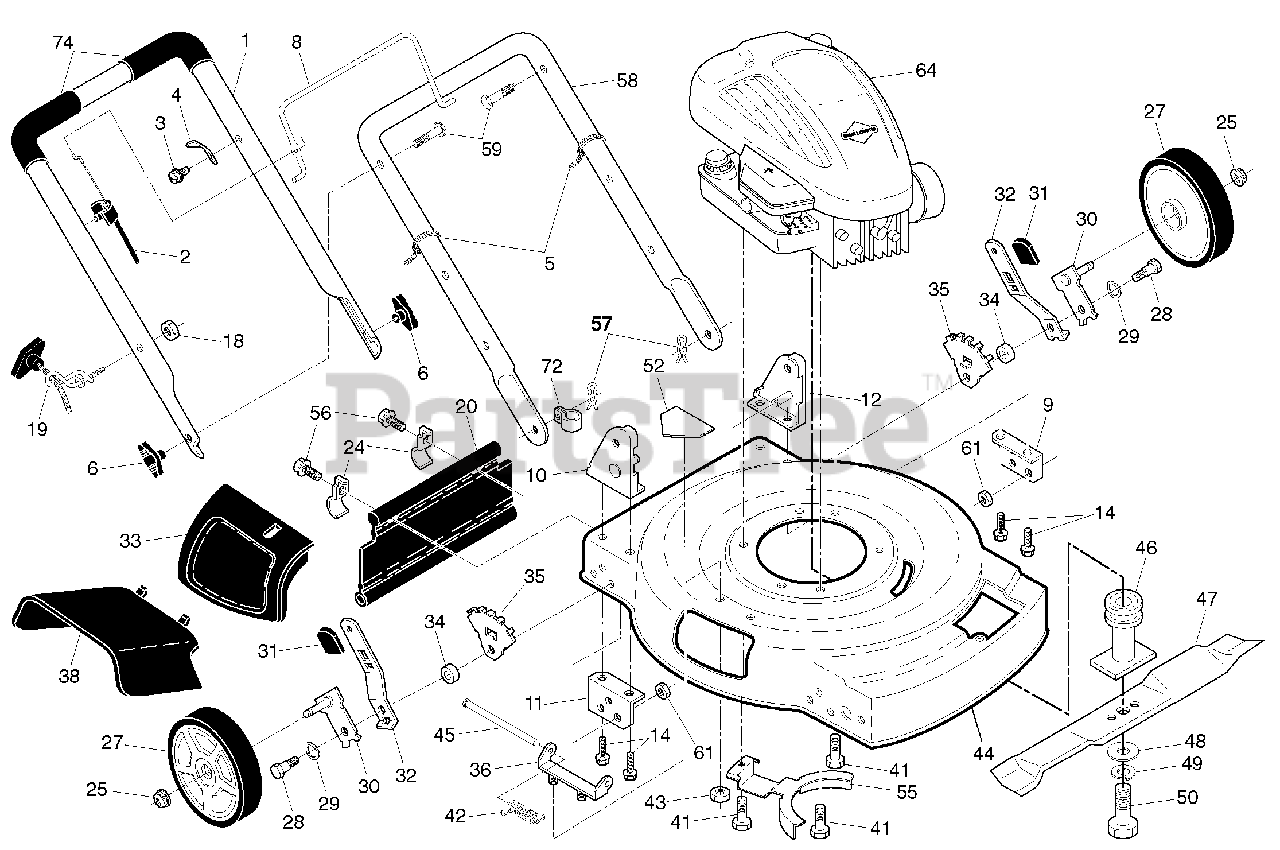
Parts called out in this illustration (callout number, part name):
1	Upper Handle Assembly
2	Engine Zone Control Cable
3	Screw
4	Bracket, Upstop
5	Wire Tie
6	Handle Knob
8	Control Bar
9	Support Bracket, Handle, LH
10	Handle Bracket, RH
11	Support Bracket, Handle, RH
12	Handle Bracket, LH
14	Screw, Thread Cutting 5/16-18 x 3/4
18	Locknut, Keps
19	Rope Guide
20	Kit, Rear Skirt
24	Clamp, Rear Skirt
25	Locknut, Hex 3/18-16
27	Wheel & Tire Assembly
28	Shoulder Bolt
29	Washer, Curved, Cylindrical
30	Axle Arm Assembly
31	Knob, Selector
32	Spring, Selector
33	Mulcher Door
34	Spacer
35	Bracket, Wheel Adjuster
36	Bracket, Housing
38	Deflector, Discharge
41	Screw, Hex Head, Threaded, Rolled 3/8-16 x 1-1/8
42	Spring, Torsion
43	Locknut, Hex 1/4-20
44	Kit, Mower Housing
45	Rod, Hinge
46	Blade Adapter / Pulley
47	Blade, 22"
48	Washer, Hardened
49	Washer, Lock, Helical
50	Screw, Hex Head, Grade 8 3/8-24 x 1-3/8
52	Decal, Danger
55	Belt Keeper
56	Screw, Hex Washer Head #10-24 x 1/2
57	Hairpin Cotter
58	Lower Handle
59	Handle Bolt
61	Locknut, Hex
72	Clip, Cable
74	Grip, Foam
74	Operator's Manual, English
74	Operator's Manual, French
74	Repair Parts Manual
